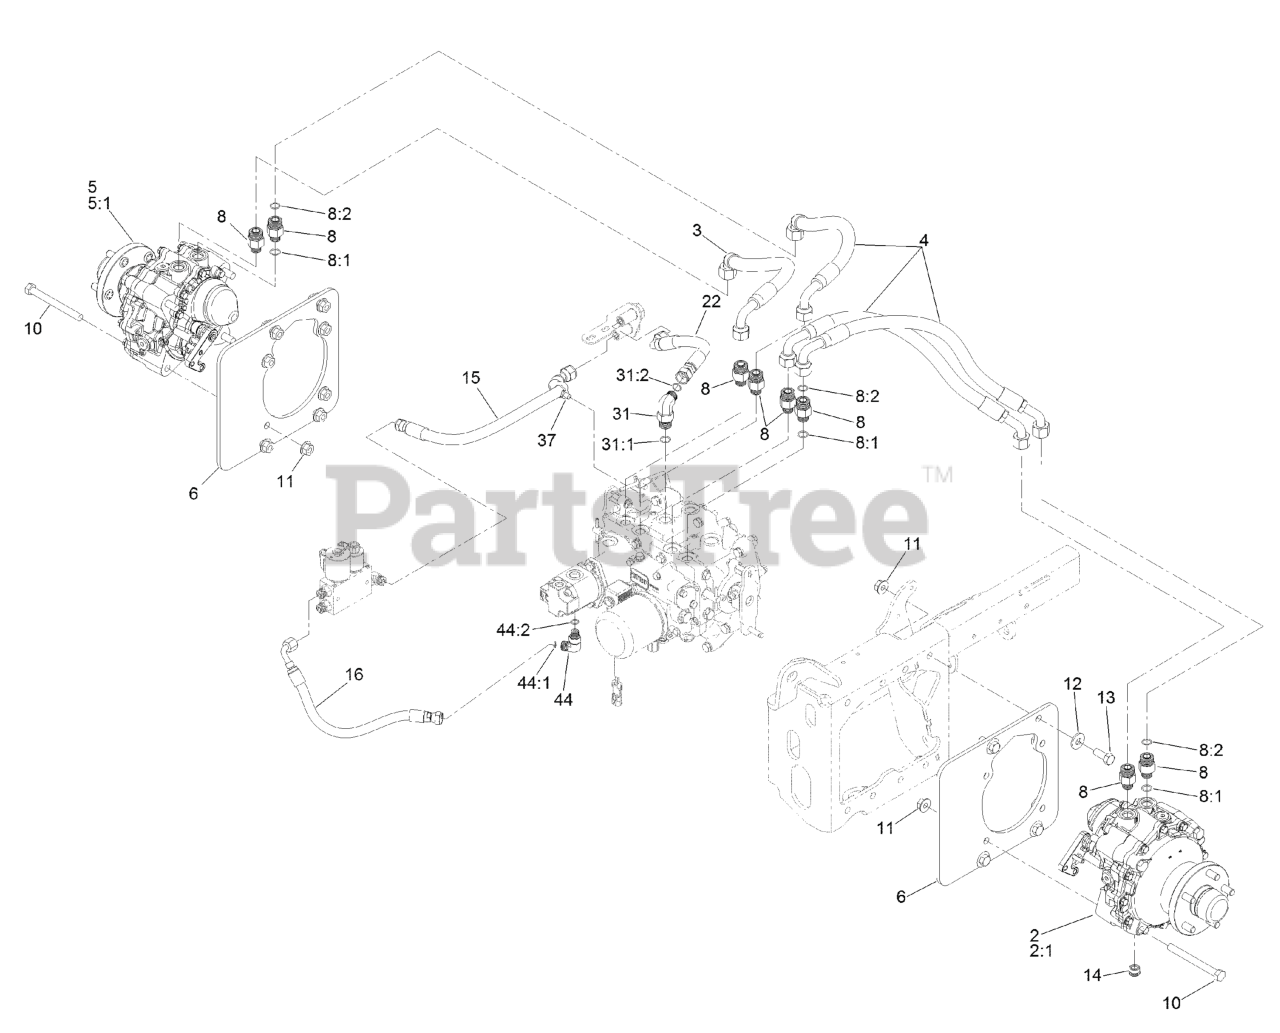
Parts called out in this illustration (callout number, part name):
2	MOTOR-HYD, LH
2:1	5 STUD WHEEL HUB KIT
3	HOSE ASM
4	HOSE ASM
5	MOTOR-HYD, RH
5:1	5 STUD WHEEL HUB KIT
6	PLATE-MOTOR
8	FITTING-STRAIGHT
8:1	O-RING
10	SCREW-HH
11	NUT-HHF
12	WASHER-SPRING
13	SCREW-HH
14	PLUG-MAGNETIC
15	HOSE ASM
16	HOSE ASM
22	HOSE ASM
31	FITTING-ELBOW, 90 DEG
31:1	O-RING
31:2	O-RING
37	CLIP-TIE
44	FITTING-ELBOW, 90 DEG
44:1	O-RING
44:2	O-RING
